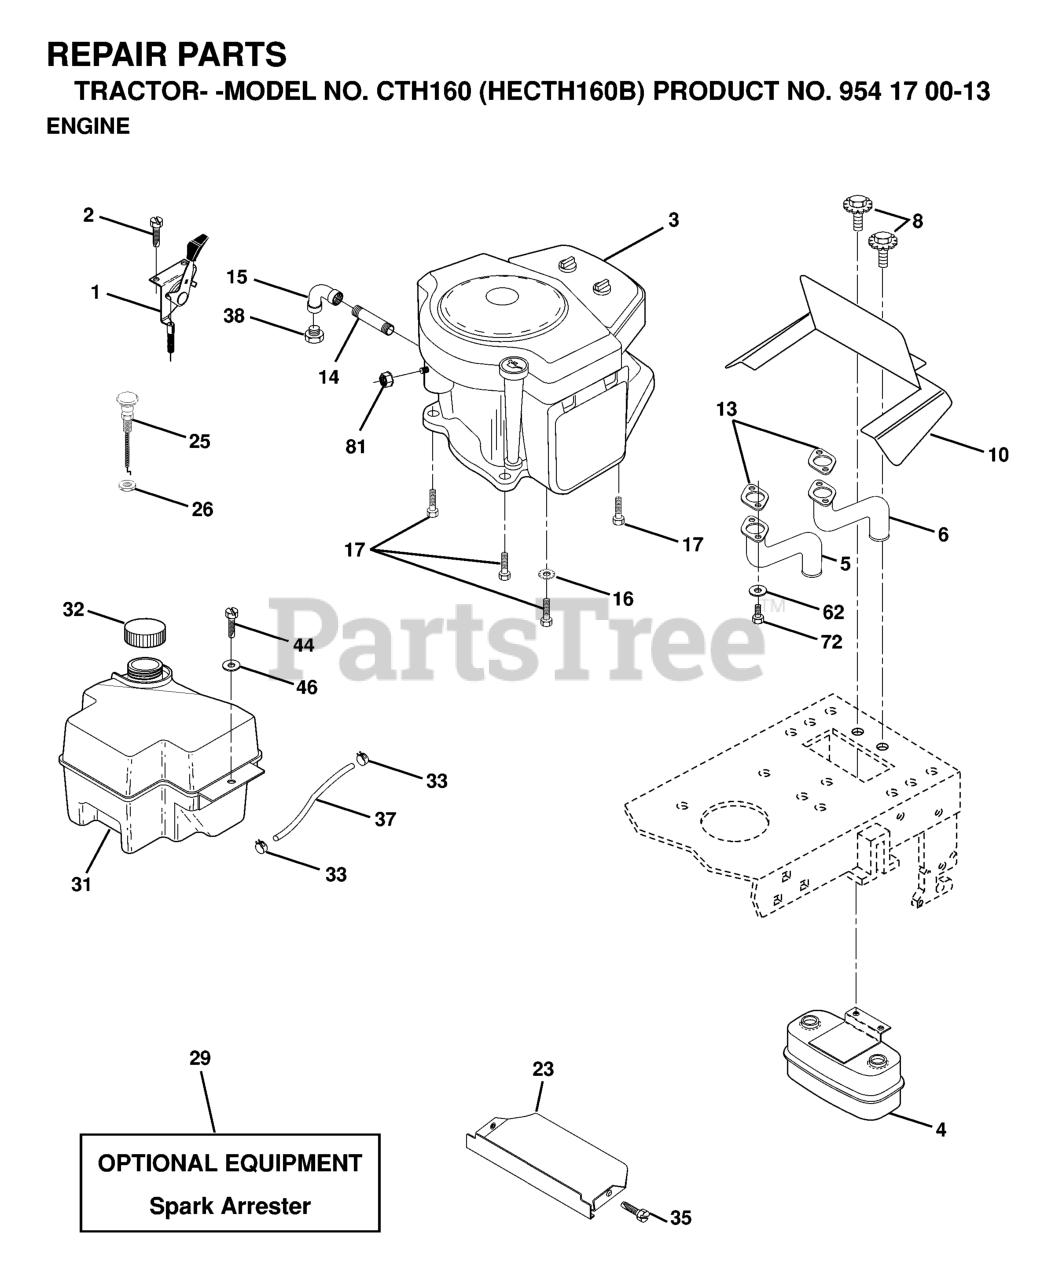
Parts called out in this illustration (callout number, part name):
1	CONTROL THROTTLE 36"
2	SCREW LT
4	MUFFLER.TWIN.CYL.LOW.TONE
5	RP.EXHAUST.TUBE.LH.BS/TWIN
6	EXHAUST.TUBE.RH.BS/TWIN
8	BOLT HEX WASHER HD 5/16-18
10	SHIELD.BROWNING.B&S
13	GASKET.MUFFLER
14	Nipple, Pipe 3/8 NPT x 4-1/2
15	ELBOW
16	LOCKWASHER
17	SCREW LT
25	CONTROL, CHOKE
26	Nut Keps 3/8 - 24 UNF
29	KIT.SPARK ARRESTOR 794945 B&S
31	FUEL TANK
32	FUEL CAP
33	HOSE CLAMP
35	SCREW.THDROL.5/16-18X3/4.TTY
37	LINE.FUEL.20
44	SCREW HEX CRT
62	WASHER.LOCK.HVY.HLCL.SPR.5/16
72	SCREW
81	NUT FLANGE 1/4-20 STARTER NUT
